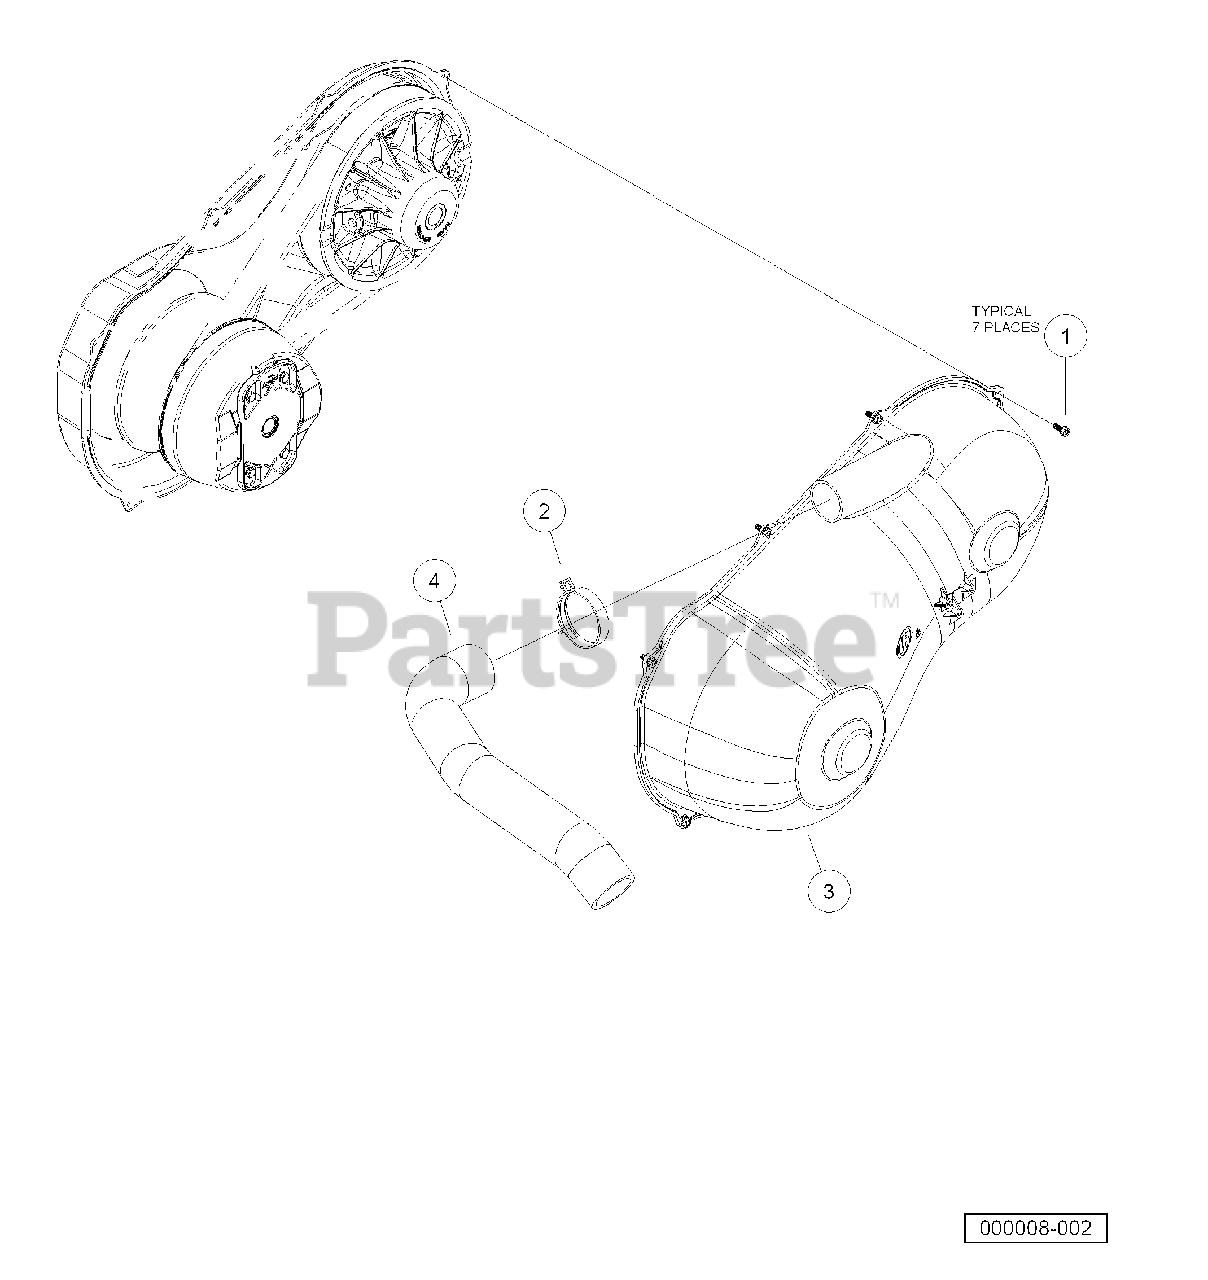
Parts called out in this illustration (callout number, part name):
1	Screw, M6 X 16 Tt Hx Fl Hd
2	Clamp, Hose, Ctb 64mm
3	Cover, CVT Outer
4	Hose, Outlet, Cvt
